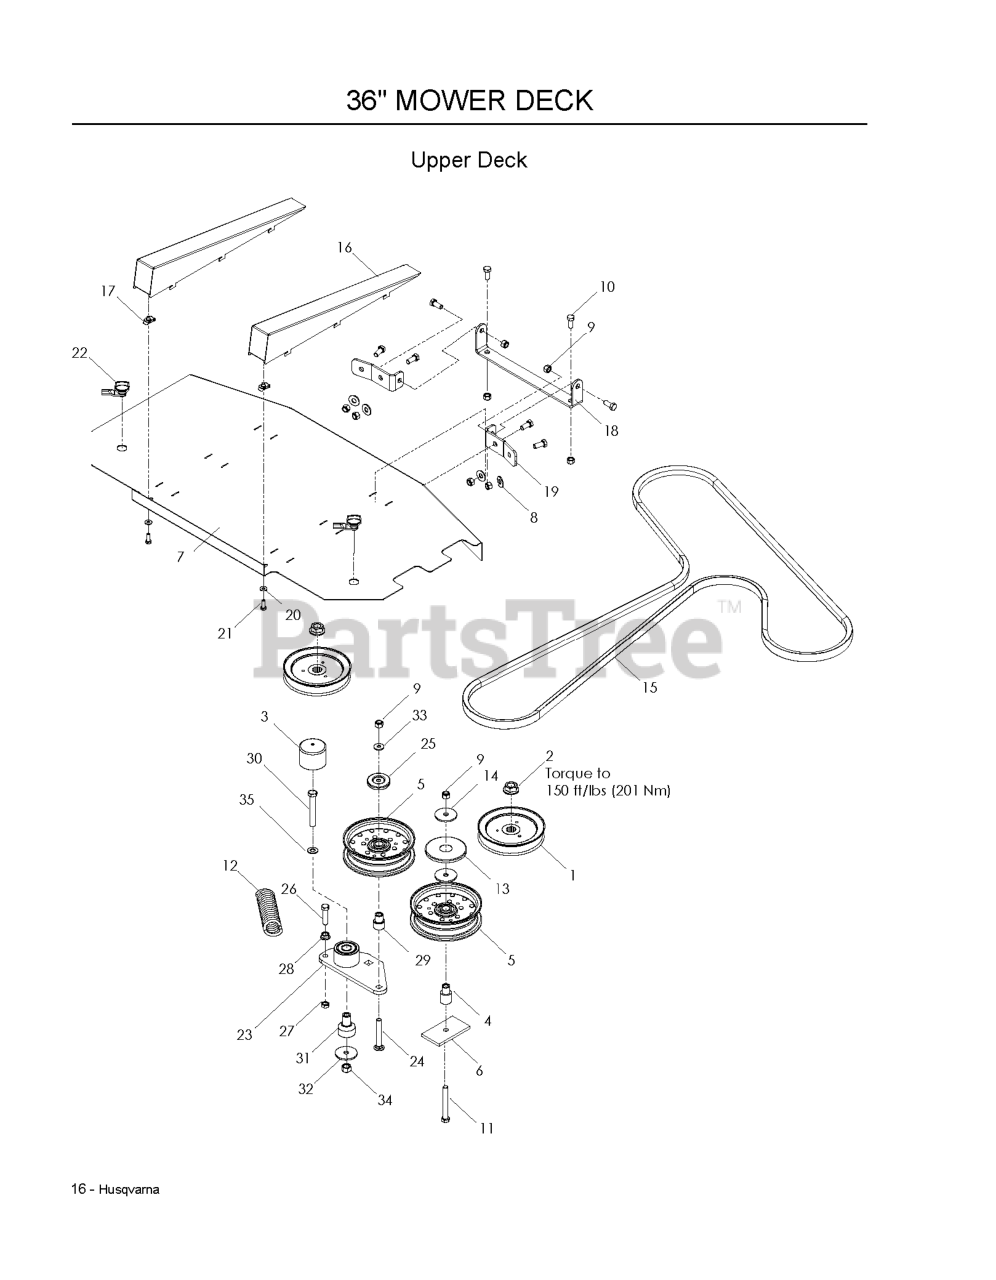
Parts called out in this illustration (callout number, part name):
1	PULLEY - 6.57
2	NUT FLANGE 3/4-16
3	CAP, VINYL
4	IDLER BUSHING
5	IDLER PULLEY
6	SUPPORT PLATE
7	COVER - BELT, 36 PAINTED
8	WASHER 3/8 FLAT
9	NUT 3/8-16 NYLOC
10	HCS 3/8-16 X 7/8 GR 5 ZD
11	HCS 3/8C X 3
13	TOP DUST CAP
14	WASHER, 3/8 SPEC
15	BELT - DECK 36 (103 L)
16	WEDGE - PAINTED
17	1/4C - U TYPE RETAINER
18	HINGE, BIN
19	BASE HINGE - PAINTED
20	WASHER 1/4 SAE
21	HCS 1/4C X 3/4 HCS
22	LATCH, SHORT WING
23	ARM-IDLER W/BRG
24	RHSNB 3/8-16 X 2.75
25	DUST SHIELD
26	HCS 3/8-16 X 1-1/2
27	NUT 3/8-16 HEX JAM
28	NUT 3/8C WHIZ
29	BUSHING, IDLER
30	HCS 1/2C X 3 1/4
31	PIVOT, BEARING
32	WASHER, SUPPORT
33	WASHER, 3/8 THICK
34	NUT 1/2-13 HEX NYLOC ZD
35	CONTACT BELLSPR 1/2
